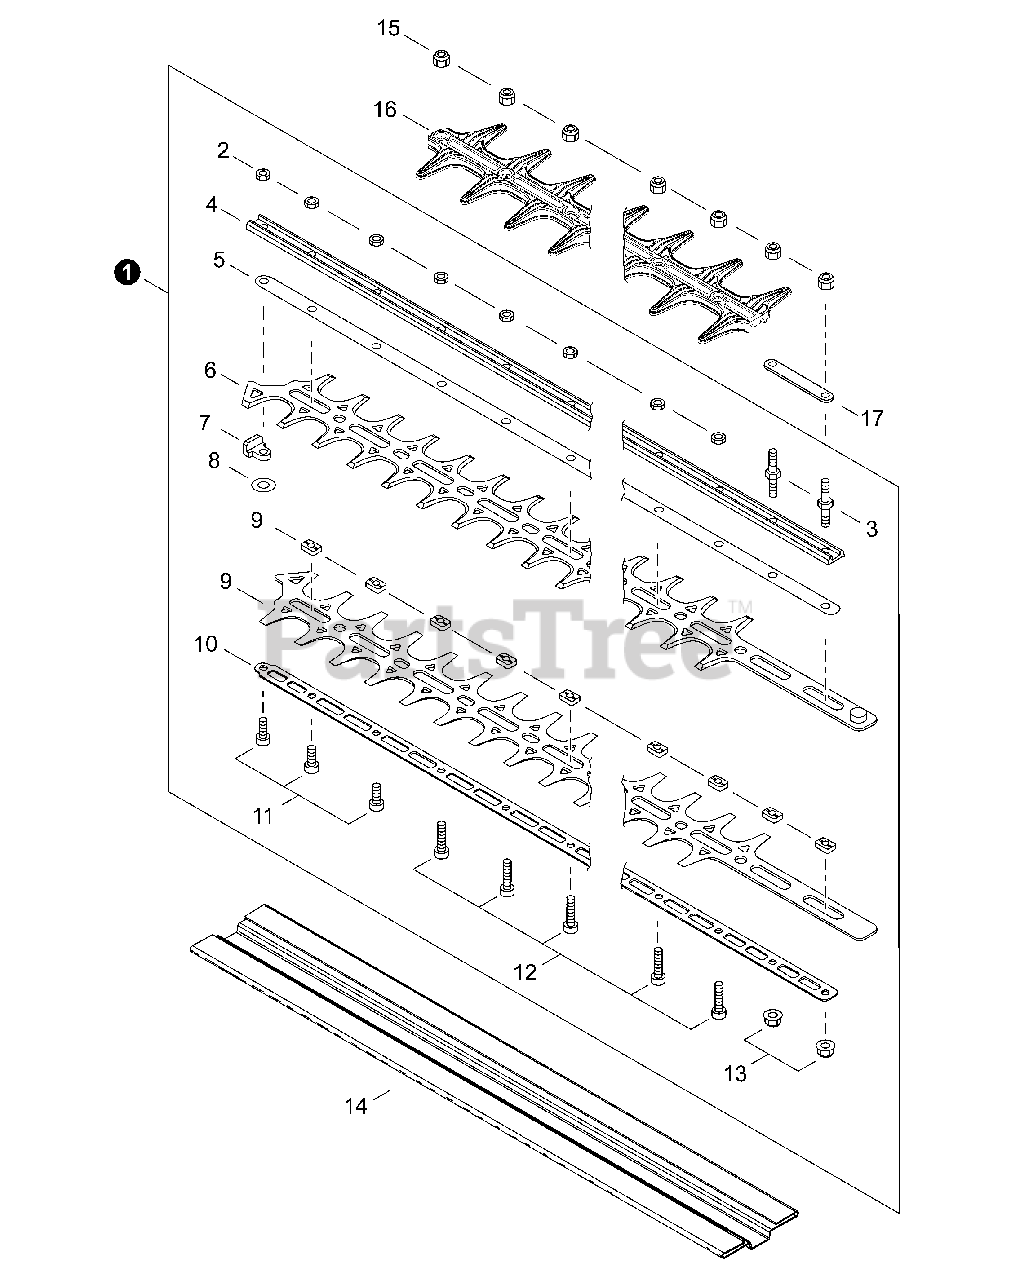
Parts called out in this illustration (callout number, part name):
1	CUTTER ASSY, 30"
3	STUD, MOUNTING M5
4	SUPPORT, CUTTER 30"
5	SUPPORT, CUTTER 30"
6	CUTTER 30"
10	SUPPORT, CUTTER 30"
11	BOLT, TORX 5×16
12	BOLT, TORX 5×25
14	SCABBARD
16	STIFFENER, BLADE
17	PLATE, EYE
